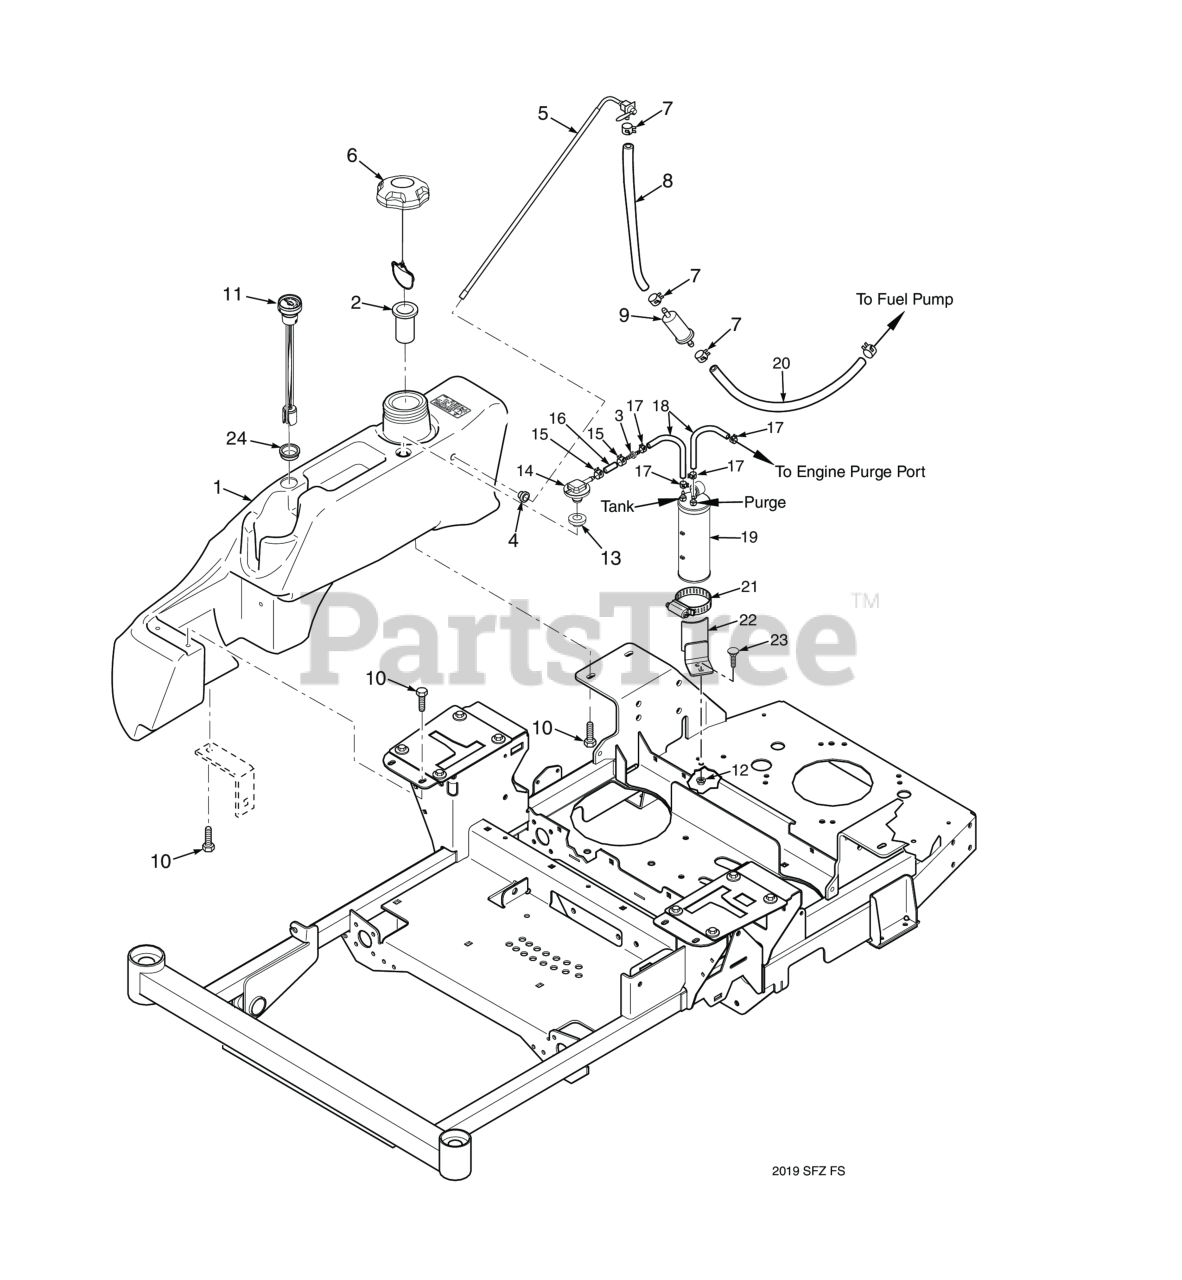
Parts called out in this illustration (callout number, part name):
1	Fuel Tank Assembly, LP - SFZ - 48
2	Tube, Fuel Tank Insert - 4"
3	Mender, 1/4 x 3/16 w/0.02 Hole
4	Bushing, 0.56" Dia. Viton
5	Fuel Tube Assembly
6	Fuel Cap w/ Tether (E.P.A.)
6	Fuel Cap w/Tethered - California Models Only
7	Clamp, Fuel Hose 1/4" Hose I.D.
8	Fuel Hose, 1/4" I.D. Non-Perm (791DFI Fuel Return) - Order by Inch
9	Fuel Filter
10	CAP SCREW, 5/16-18 X 1/2" SERRATED FLANGE HEX
11	Fuel Gauge (requires #6)
12	Nut, Serrated Flange 5/16-18 (Right Front Engine Mounting, Briggs and Kohler Only)
13	Grommet, Viton,
14	Remote Vent, No Valve
15	CLAMP, FUEL HOSE(KAWASAKI ONLY)
16	Hose, 1/4" Vapor Recovery (order by inch)
17	Clamp, Vapor Recovery Hose 3/16"
18	Hose, Vapor Recovery 3/16" (order by inch)
19	Carbon Canister - SVR-52V / SVR-61V
19	Dust Filter, Carbon Canister
20	Fuel Hose
21	Clamp, 3-1/2" Max. Dia.
22	Bracket Weldment, Kohler Models
23	Bolt, 5/16-18 x .75 RHSN Carriage
24	Grommet, Fuel Gauge
